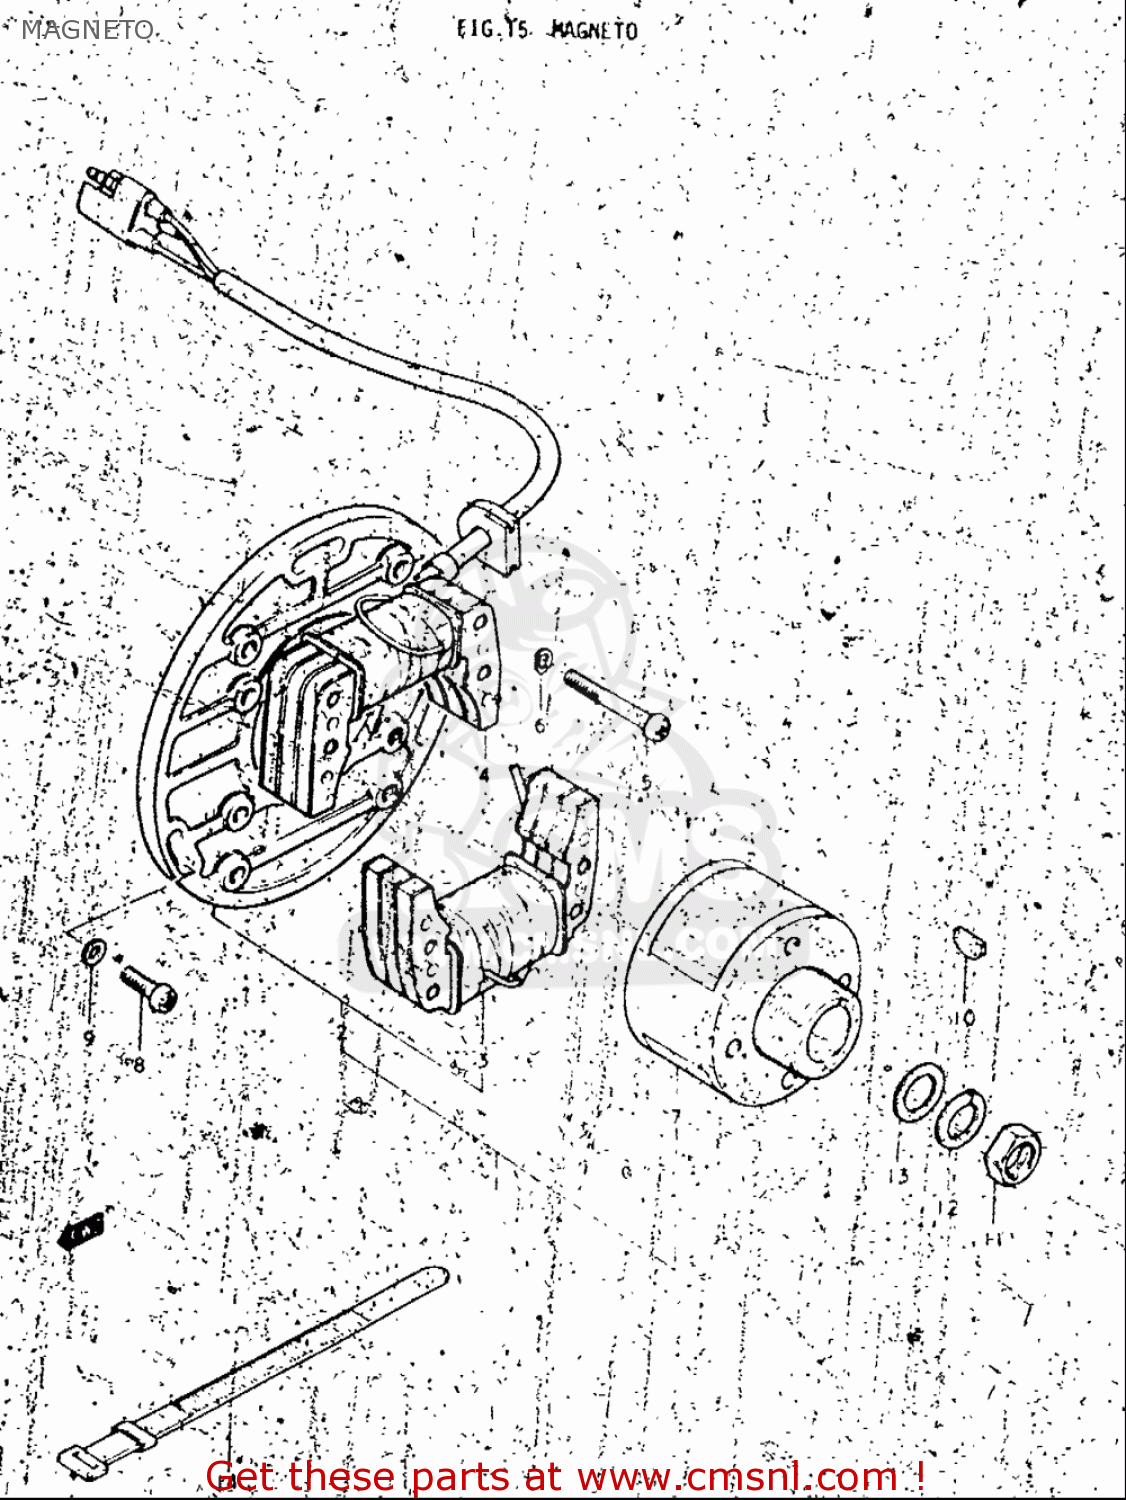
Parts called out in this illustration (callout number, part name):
5	SCREW
6	WASHER,LOCK
8	SCREW
9	WASHER
10	KEY
11	NUT
12	WASHER,LOCK
13	WASHER(14X27X3)
14	CLAMP(L:120)
